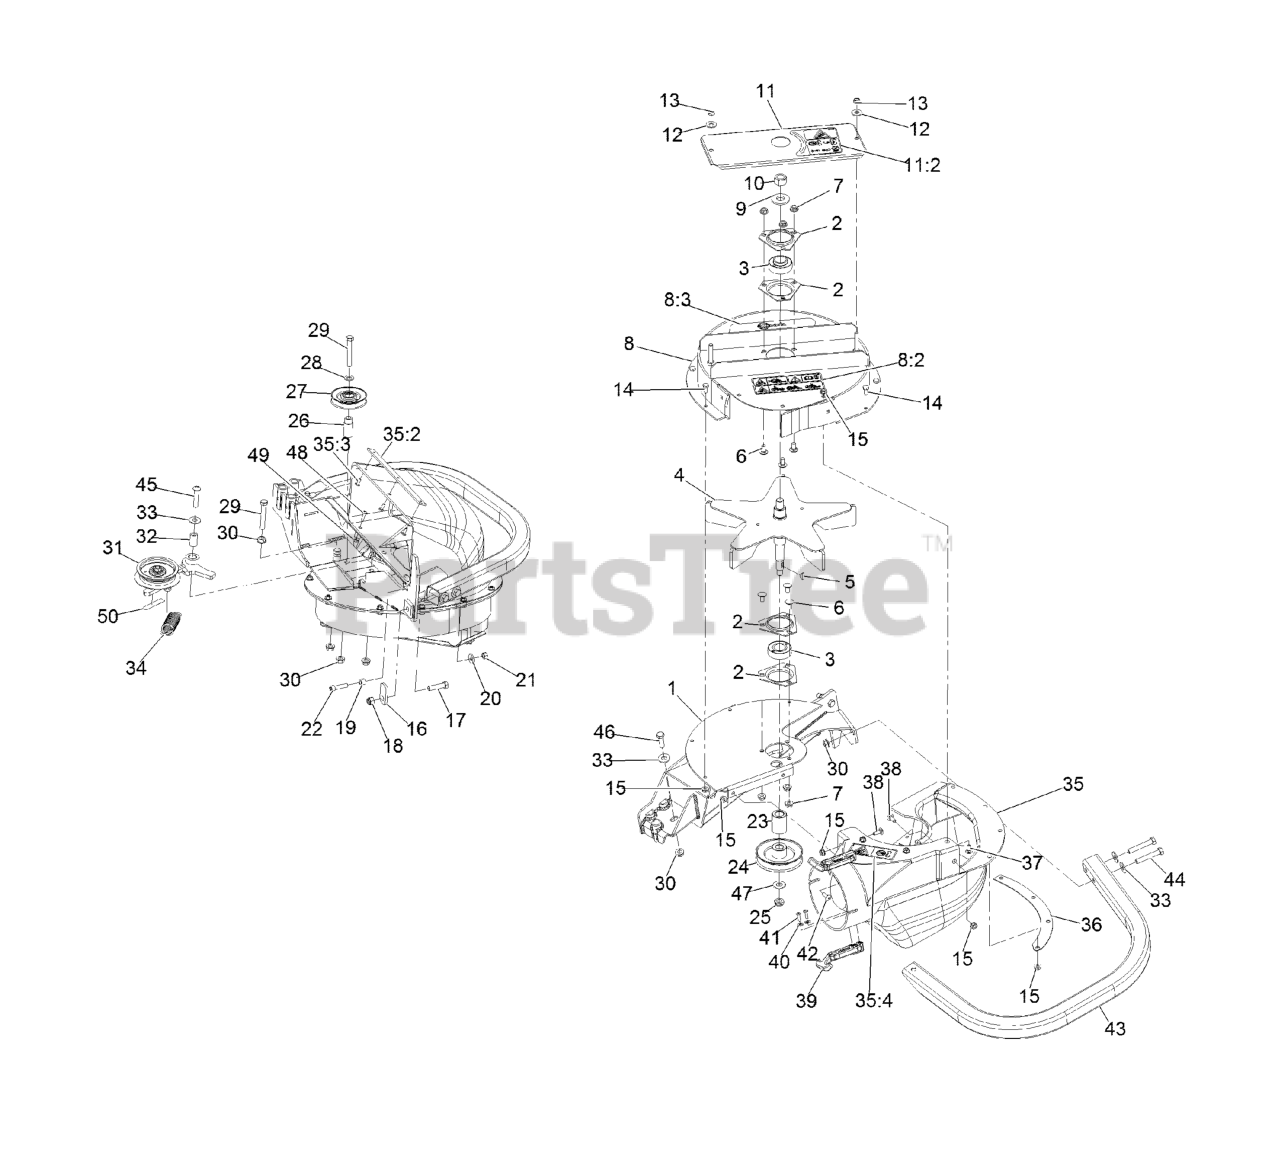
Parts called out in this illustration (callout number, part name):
1	FRAME- BLOWER
2	HOUSING-FLANGE
3	BEARING
4	IMPELLER
5	KEY-WOODRUFF
6	SCREW-CARR
8	UPPER-HOUSING W/DECAL
8:2	DECAL-ULTRAVAC S-SERIES
8:3	DECAL-WARNING
9	WASHER-SPRING
10	NUT-HEX
11	COVER-BEARING W/DECAL
11:2	DECAL-WARNING
12	WASHER-FLAT
13	NUT-LOCK, NI
14	SCREW-HH
16	LATCH-CATCHER, GRASS
17	SCREW-HH
18	NUT-LOCK, NI
19	BUSHING, LOCATOR
20	WASHER-SPRING
21	NUT-HEX
22	SCREW-HSH
24	SHEAVE-BLOWER
25	NUT-LOCK, NI
27	IDLER-INSIDE
28	WASHER-FLAT
29	SCREW-HH
30	NUT-HHF, WHIZ
31	ASM, IDLER
32	BUSHING-PIVOT, IDLER
33	WASHER-FLAT
34	SPRING-IDLER
35	ASM,BLOWER CHUTE LHP
35:2	PLATE-REINFORCEMENT
35:3	RIVET-BLIND
35:4	Decal-Blower-Impeller Hazard
36	PLATE-BACKING, BLOWER
37	SCREW-CARR
38	BOLT-CARR
39	LATCH-RUBBER
40	WASHER-FLAT
41	SCREW-PPH
44	SCREW-HH
45	SCREW-HSBH
46	SCREW-HH
47	WASHER-FLAT
48	SCREW-HEAD, TRUSS
50	DECAL-WARNING
